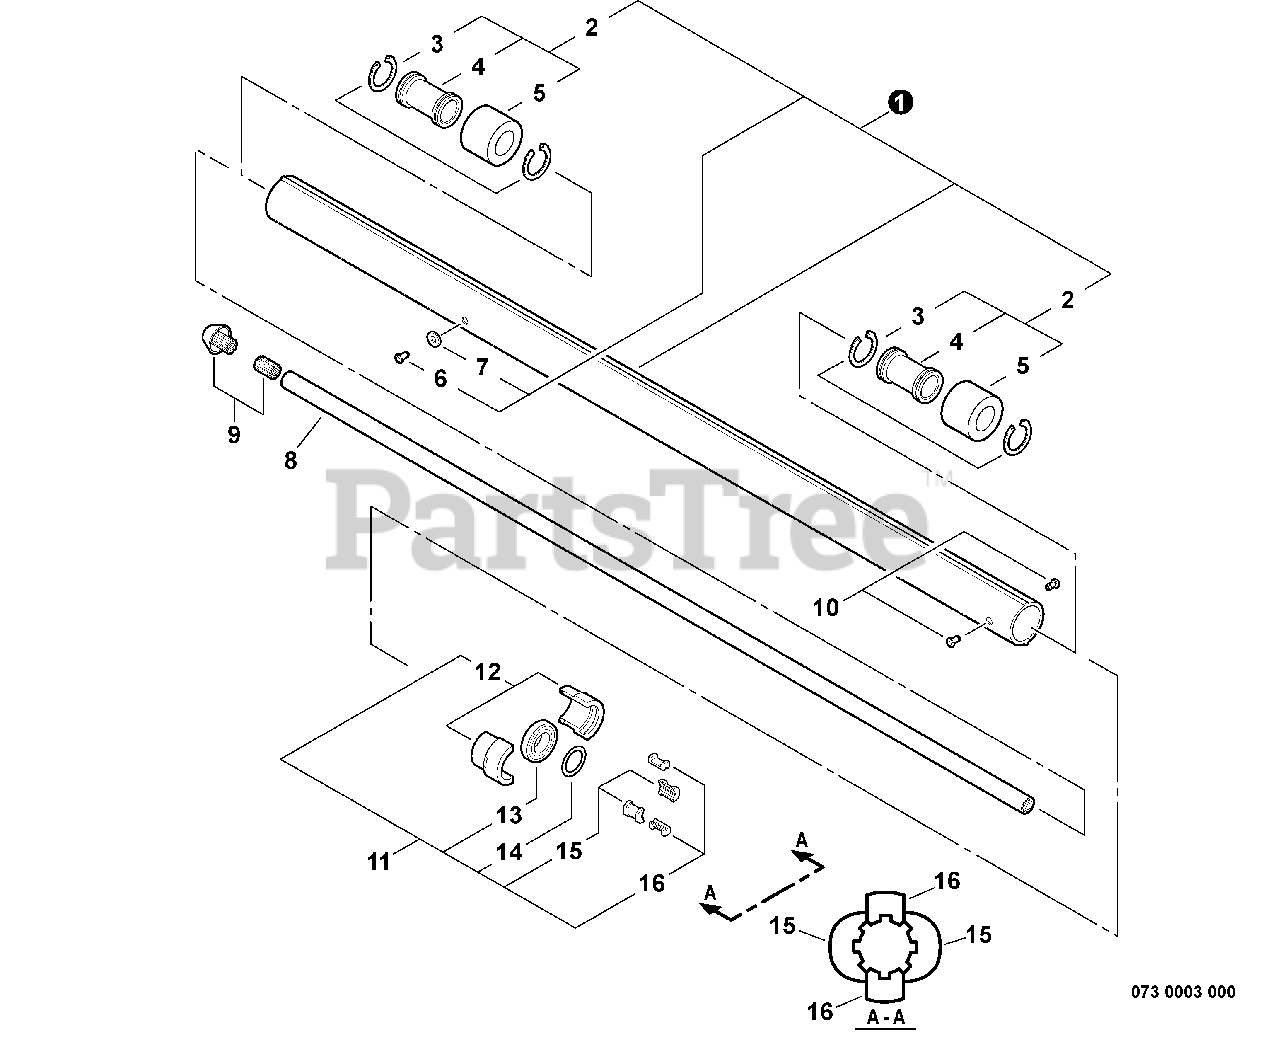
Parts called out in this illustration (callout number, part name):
1	MAIN PIPE ASSY - BLACK
2	DRIVESHAFT GUIDE ASSY
3	RING, RETAINING
4	GUIDE, DRIVESHAFT
5	PAD, FOAM
7	WASHER - 5
8	DRIVESHAFT - UPPER
9	ADAPTER, DRIVESHAFT - UPPER
11	BEARING HOLDER KIT
12	BEARING HOLDER KIT
13	BEARING, BALL - 6002
14	WASHER - SPRING
15	HOLDER, INNER BEARING - LARGE
16	HOLDER, INNER BEARING - SMALL
